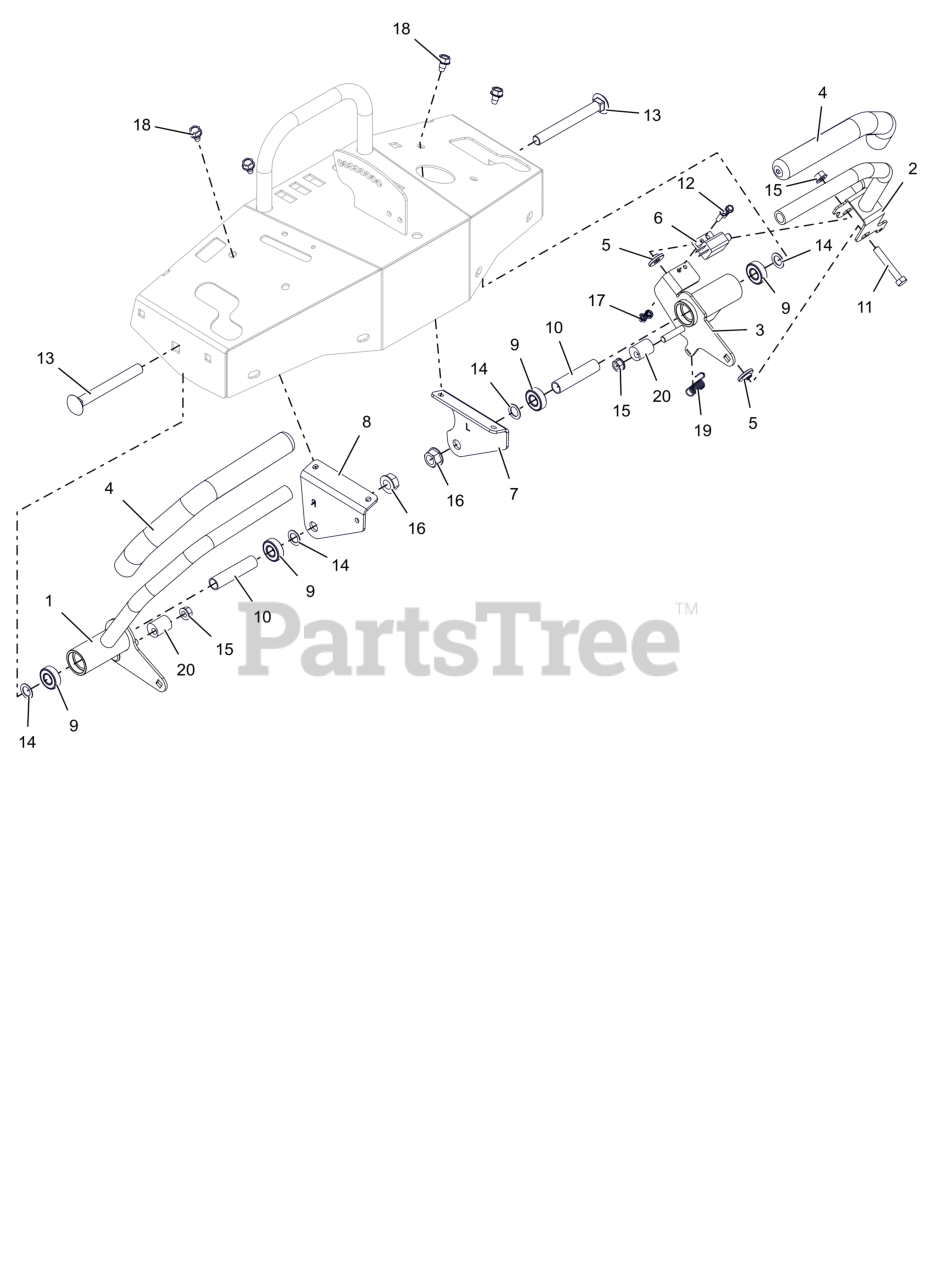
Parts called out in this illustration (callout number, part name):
1	WLDMT, RH DRIVE CONTROL (BLACK)
2	WLDMT, LH HANDLE ASM (BLACK)
3	WLDMT, LH DRIVE CONTROL (BLACK)
4	GRIP, HANDLEBAR
5	BSHG, FLG .325X.499X.26X.88
6	SWITCH- SINGLE POLE N.O.
7	BRKT, LH DRIVE CONTROL MTG (BLACK)
8	BRKT, RH DRIVE CONTROL MTG (BLACK)
9	BEARING, .500X1.125X.375
10	SPCR, .510 X .625 X 2.750
11	BLT, HEX .31-18X2.00 G5 ZCC
12	BLT, HWH #10-24X.75 ZCC
13	BLT,RHSN .50-13X4.50 G5 ZCC
14	WSHR-FL-STL 0.52X0.81X0.033 ZCC
15	NUT,LK-CTR-FLG .31-18 GF ZCC
16	NUT-LK-CTR-FLG .500-13 GG ZCC
17	NUT, KEPS #10-24 ZCC
18	SCR,TAP .312-18X.50 HWH TR ZCC
19	SPRING, EXT. .043X.438X1.64
20	ECCENTRIC
